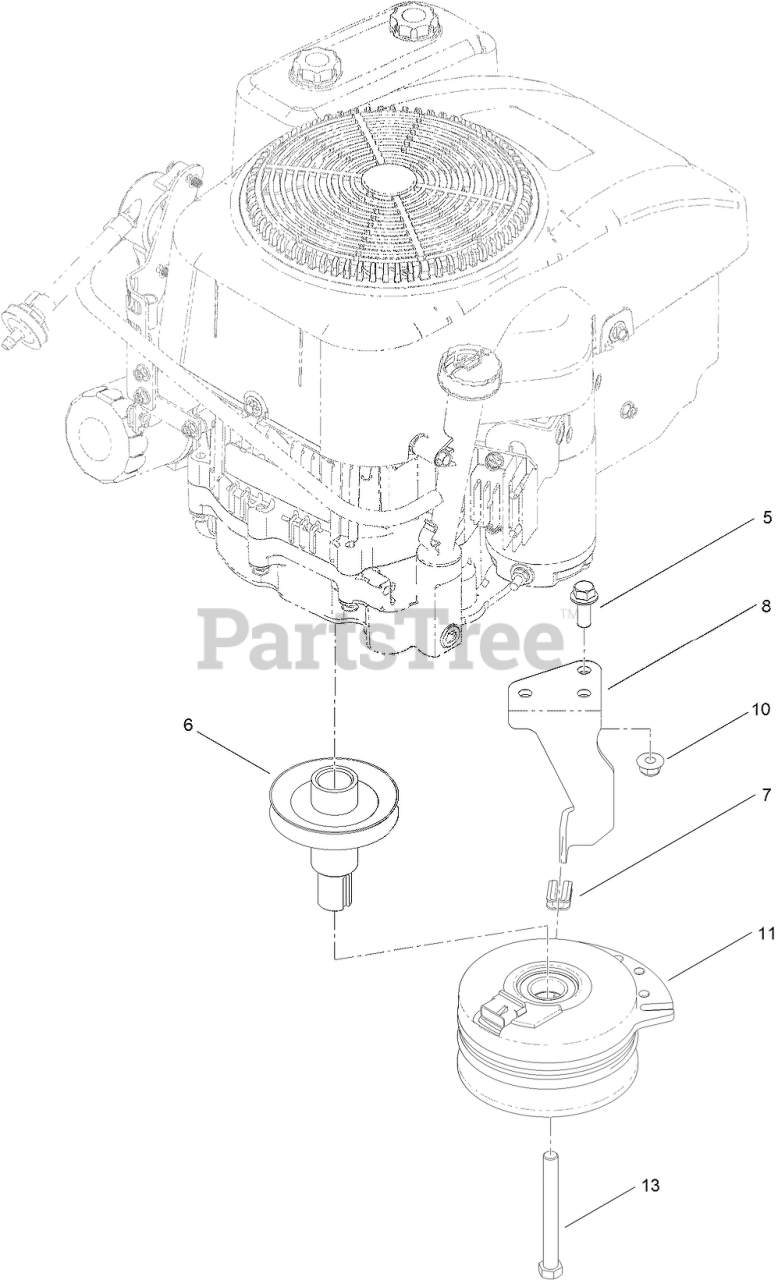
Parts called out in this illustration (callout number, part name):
5	SCREW-HHF
6	PULLEY-ENGINE
7	ISOLATOR-CLUTCH
8	STOP-CLUTCH
10	NUT-HF, NI
11	CLUTCH-ELECTRIC
13	SCREW-HH
